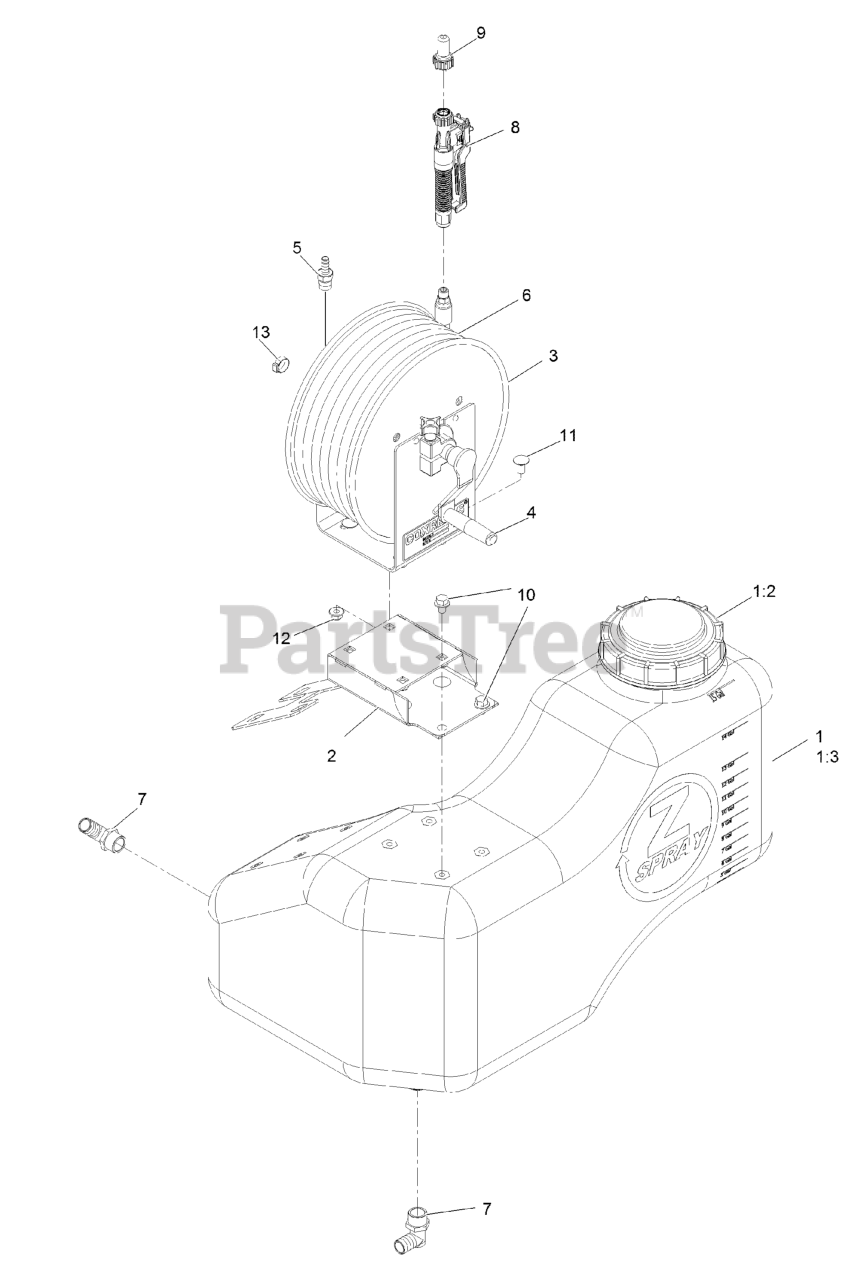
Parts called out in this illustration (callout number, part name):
1	ASM-TANK, LT
1:2	CAP-TANK, SPRAY
1:3	FITTING-BULKHEAD
2	MOUNT-REEL, HOSE
3	REEL-HOSE
4	Crank-Reel
5	FITTING,MALE
6	HOSE-SPRAY, 75'
7	FITTING-ELBOW, 90
8	GUN-SPRAY, SPOT
9	TIP-SPRAY, #12 SPOT
10	Screw-HHF
11	SCREW-CARRIAGE
12	Nut-Hex Flange
13	CLAMP-OETIKER, 167
